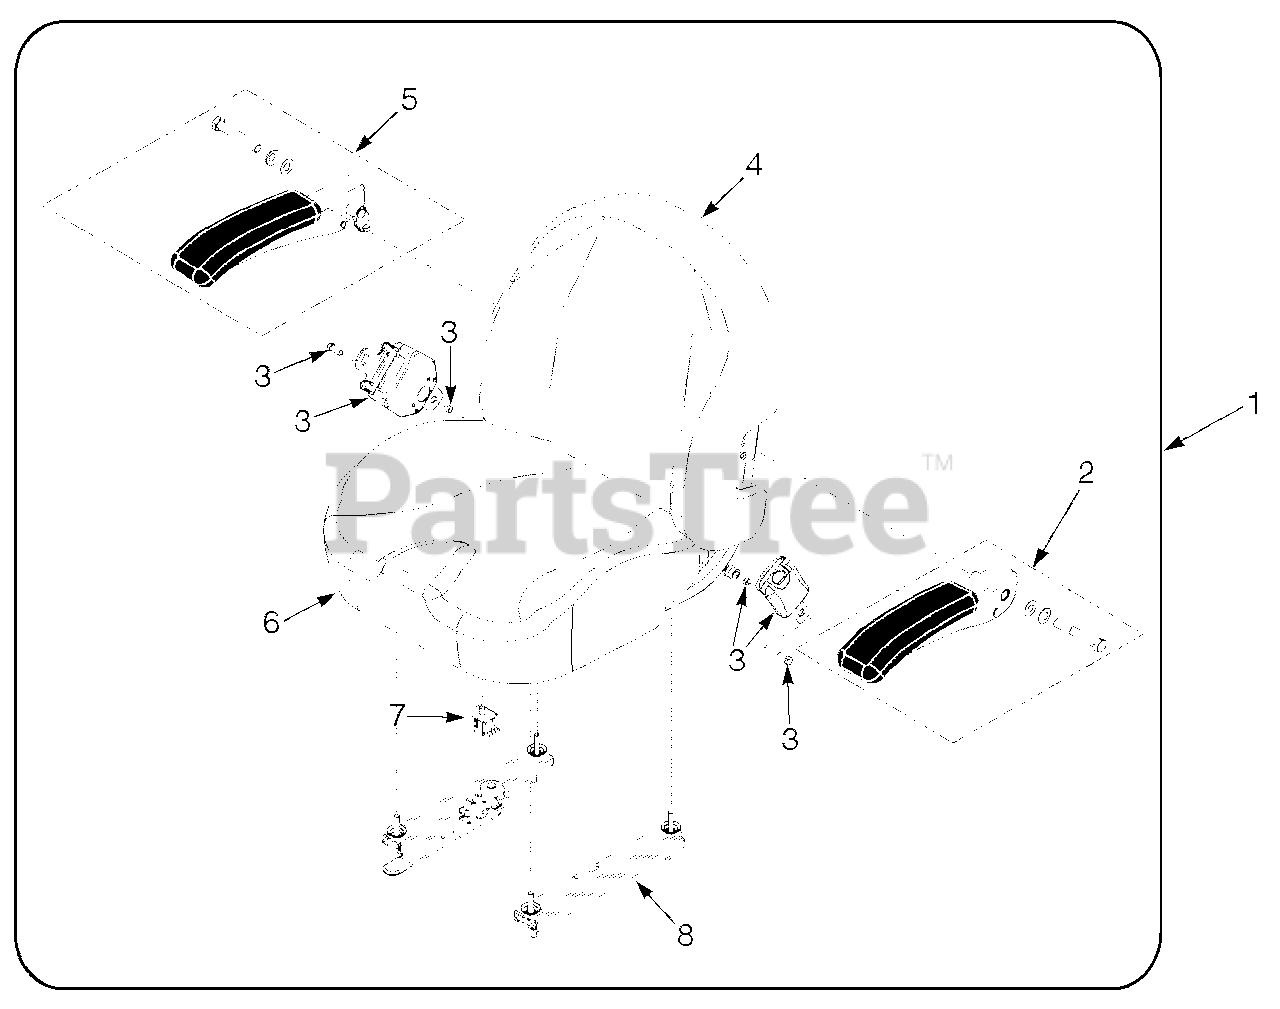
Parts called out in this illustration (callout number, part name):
1	Seat Assembly
2	Armrest Kit, LH
3	Seatbelt Kit
4	Back Cover
5	Armrest Kit, RH
6	Cushion Cover
7	Switch
8	Track Set
